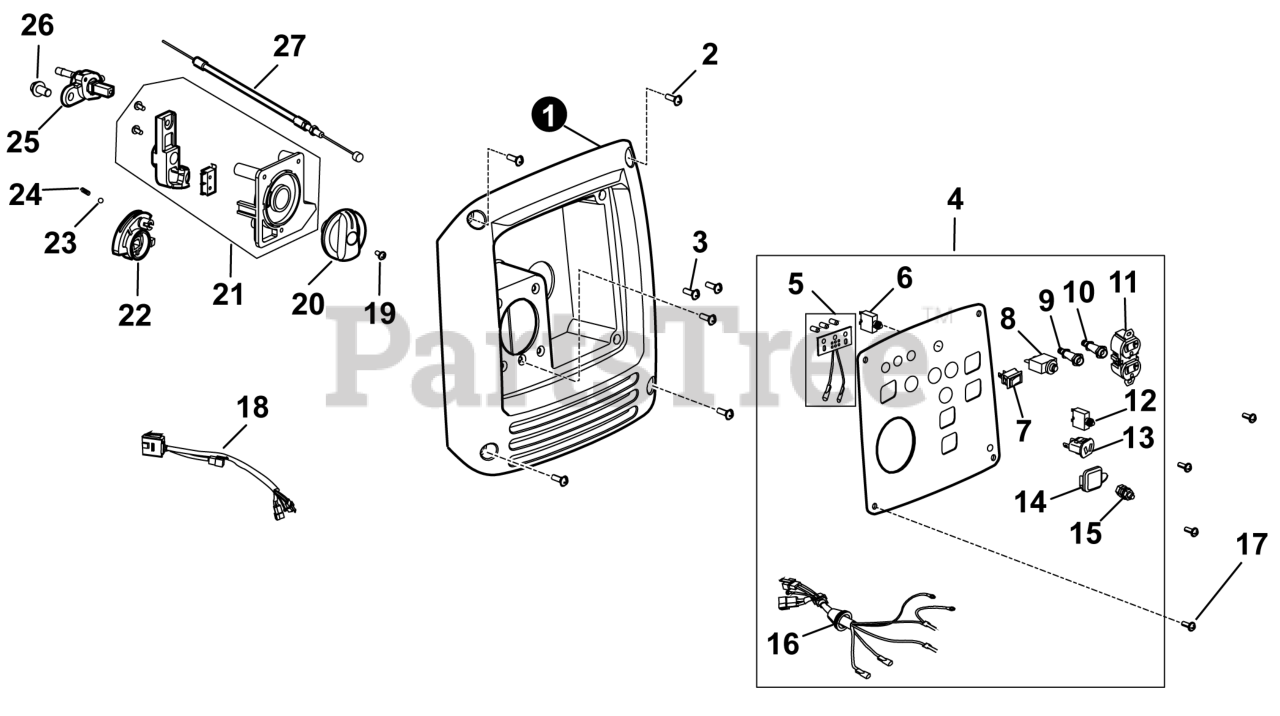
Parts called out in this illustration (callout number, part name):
1	HOUSING, PANEL
3	SCREW, CROSS GROOVE PAN
4	PANEL, CONTROL
5	INDICATOR ASSY.
6	BREAKER, CIRCUIT
7	SWITCH, AUTO THROTTLE
8	SWITCH, RESET
9	SOCKET, PARALELL (RED)
10	SOCKET, PARALELL (BLACK)
11	SOCKET, POWER SUPPLY
12	SWITCH, DC CHARGE RESET
13	SOCKET, D.C. CHARGE
14	SOCKET, USB PORT
15	TERMINAL, GROUND BOLT
16	HARNESS, CONTROL PANEL WIRING
17	SCREW, CROSS GROOVE PAN
18	REGULATOR, VOLTAGE
21	SWITCH ASSY.
22	COVER, BOARD
23	BALL, STEEL
24	SPRING, STOPPER ADJUSTING
25	VALVE, FUEL SHUT OFF
27	CABLE, CHOKE
